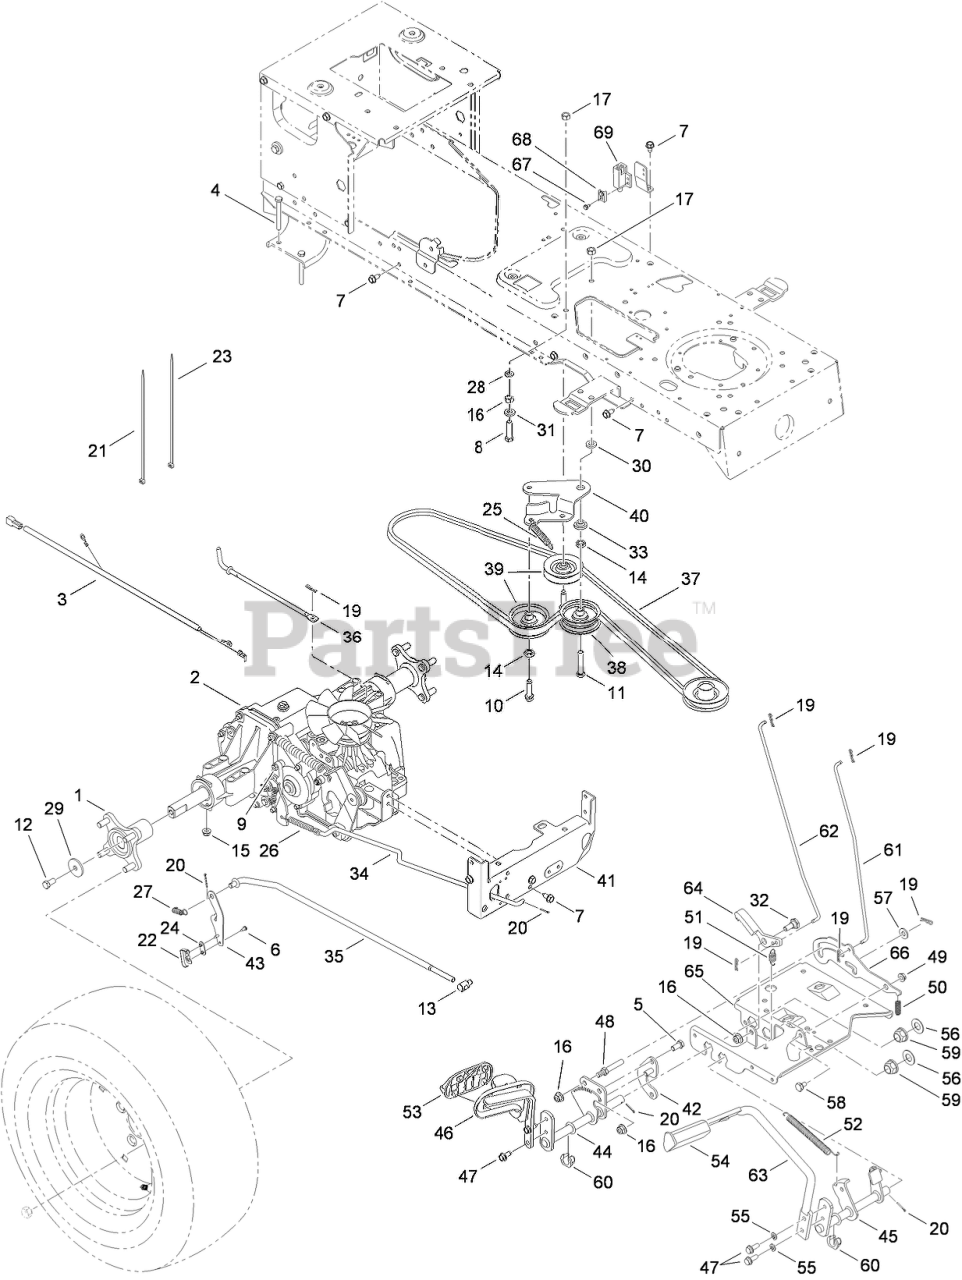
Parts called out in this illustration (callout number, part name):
1	WHEEL HUB ASM
2	TRANSMISSION ASM
3	HARNESS ASM
4	SCREW-HEX
5	SCREW-HH
6	SCREW-HWHTF
7	SCREW-TAP
8	SCREW-HH
9	SCREW-HWHTF
10	SCREW-TAP
11	SCREW-HH
12	SCREW-HH
13	FERRULE
14	NUT-JAM
15	NUT-LOCK, FLANGE
16	NUT-LOCK, FLANGE
17	NUT-LOCK, FLANGE
19	PIN-COTTER
20	PIN-COTTER
21	TIE-CABLE
22	SWITCH-SPRING, SHORT
23	TIE-CABLE
24	PLATE-INSULATOR
25	SPRING-EXTENSION
26	SPRING-EXTENSION
27	SPRING-EXTENSION
28	WASHER-LOCK
29	WASHER-FLAT
30	WASHER-FLAT
31	WASHER-FLAT
32	BOLT-SHOULDER
33	SPACER-SHOULDER
34	ROD-BRAKE
35	ROD-CONTROL
36	ROD-DISENGAGE
38	PULLEY-IDLER, FLAT
39	PULLEY-IDLER, Y TYPE
40	BRACKET-IDLER, CENTER DOUBLE
41	BRACKET-TRANSMISSION
42	BRACKET-CONTROL
43	BRACKET-ACTUATOR
44	CONTROL ASM
45	SPEED CONTROL ASM
46	CONTROL PEDAL ASM
47	SCREW-HWH
49	NUT-LOCK, FLANGE
50	SPRING
51	SPRING-EXTENSION
52	SPRING-EXTENSION
53	PAD-PEDAL
54	PAD-BRAKE
55	WASHER-LOCK
56	WASHER-FLAT
57	Washer-Flat
58	BOLT-SHOULDER
59	BEARING-FLANGE
60	BEARING-FLANGE, HEX (SPLIT)
61	ROD-BRAKE, LOCK
62	ROD-CONTROL, CRUISE
63	PEDAL-BRAKE
64	LATCH-CRUISE
65	BRACKET-SUPPORT, STEERING
66	BRACKET-LOCKOUT
67	SCREW-TAP
68	PLATE-SWITCH
69	SWITCH-INTERLOCK
